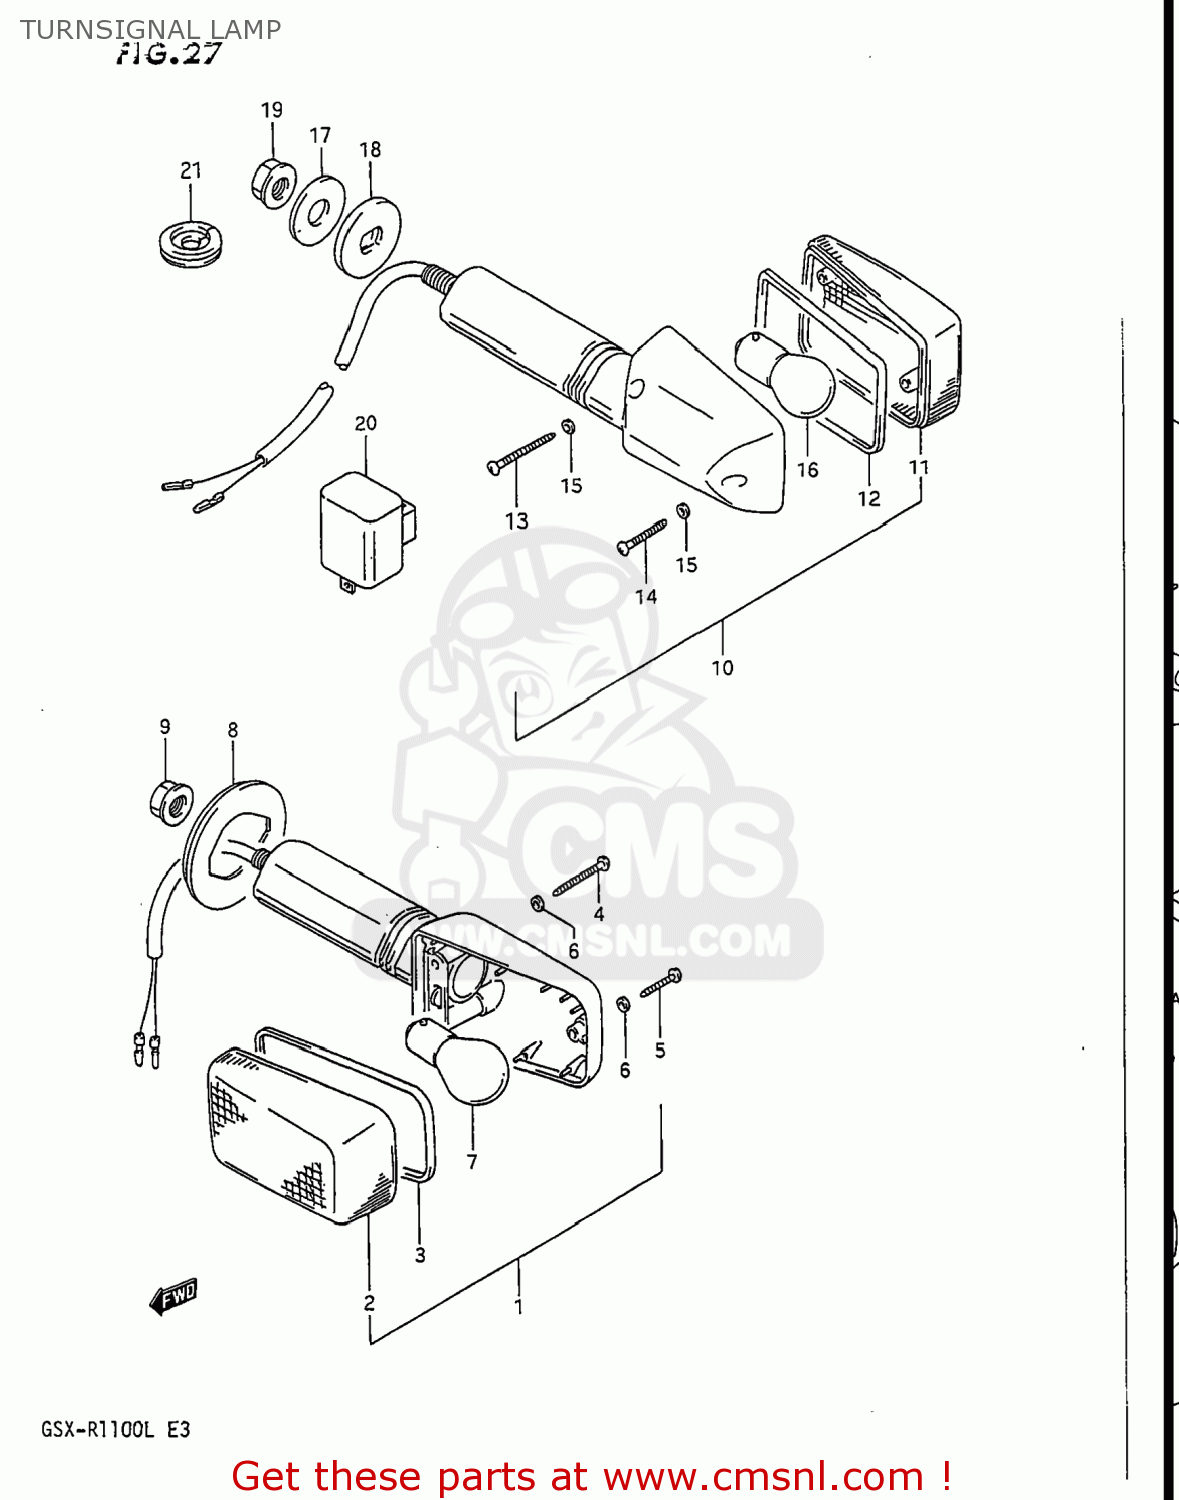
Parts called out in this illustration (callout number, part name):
1	LAMP ASSEMBLY,FRONT TURN SIGNAL
2	LENS
3	GASKET (NAS)
4	SCREW(3X30)
5	SCREW
6	GASKET (NAS)
7	BULB(12V21W)
8	GROMMET
9	NUT
10	LAMP ASSY,FR TURN SIGNAL
11	LENS
12	GASKET (NAS)
13	SCREW(3X30)
14	SCREW
15	GASKET (NAS)
16	BULB(12V21W)
17	WASHER(10.5X30X3.2)
18	SPACER,RR TURNSIGNAL
19	NUT
20	RELAY ASSEMBLY,TURN SIGNAL
21	GROMMET
